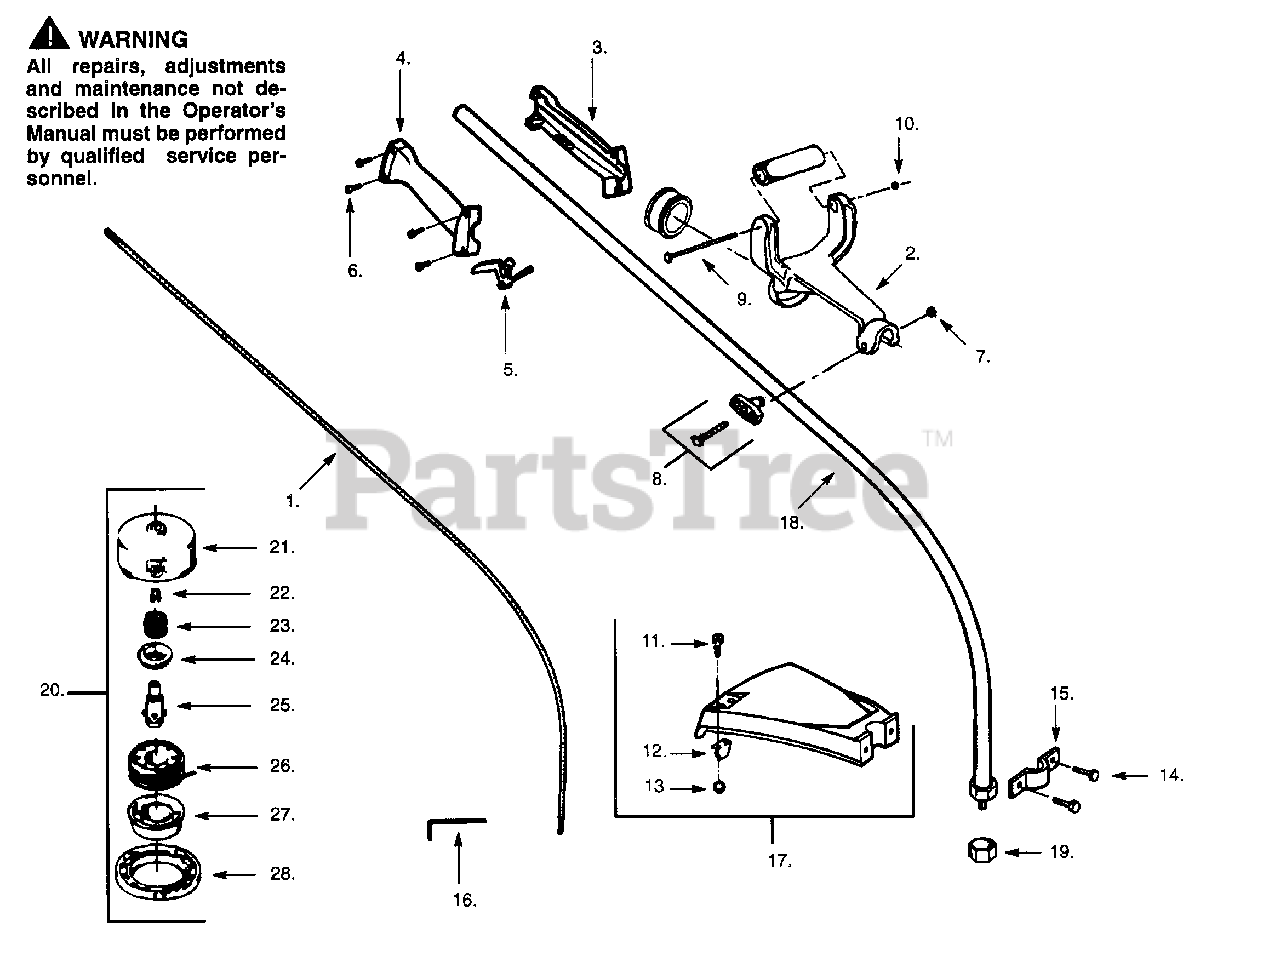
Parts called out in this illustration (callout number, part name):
1	Drive Shaft
2	Antivibe Handle Ass'y. (Inc. 10 & 9)
3	Throttle Hsg. (Left)
4	Throttle Hsg. (Right)
5	Throttle Lever
8	"T" Handle
12	Line Limiter
13	Locknut
15	Bracket Shield
16	Hex Wrench (5/32)
17	Shield Kit Ass'y. (Inc. 11,12,13,14)
18	Drive Shaft Hsg.
19	Dust Cup
20	Cutting Head Ass'y. (Inc. 21-28)
21	Hub Ass'y.
22	Line Saver
24	Spring Cap
25	Drive Gear
26	Spool w/Line
27	Release Button
